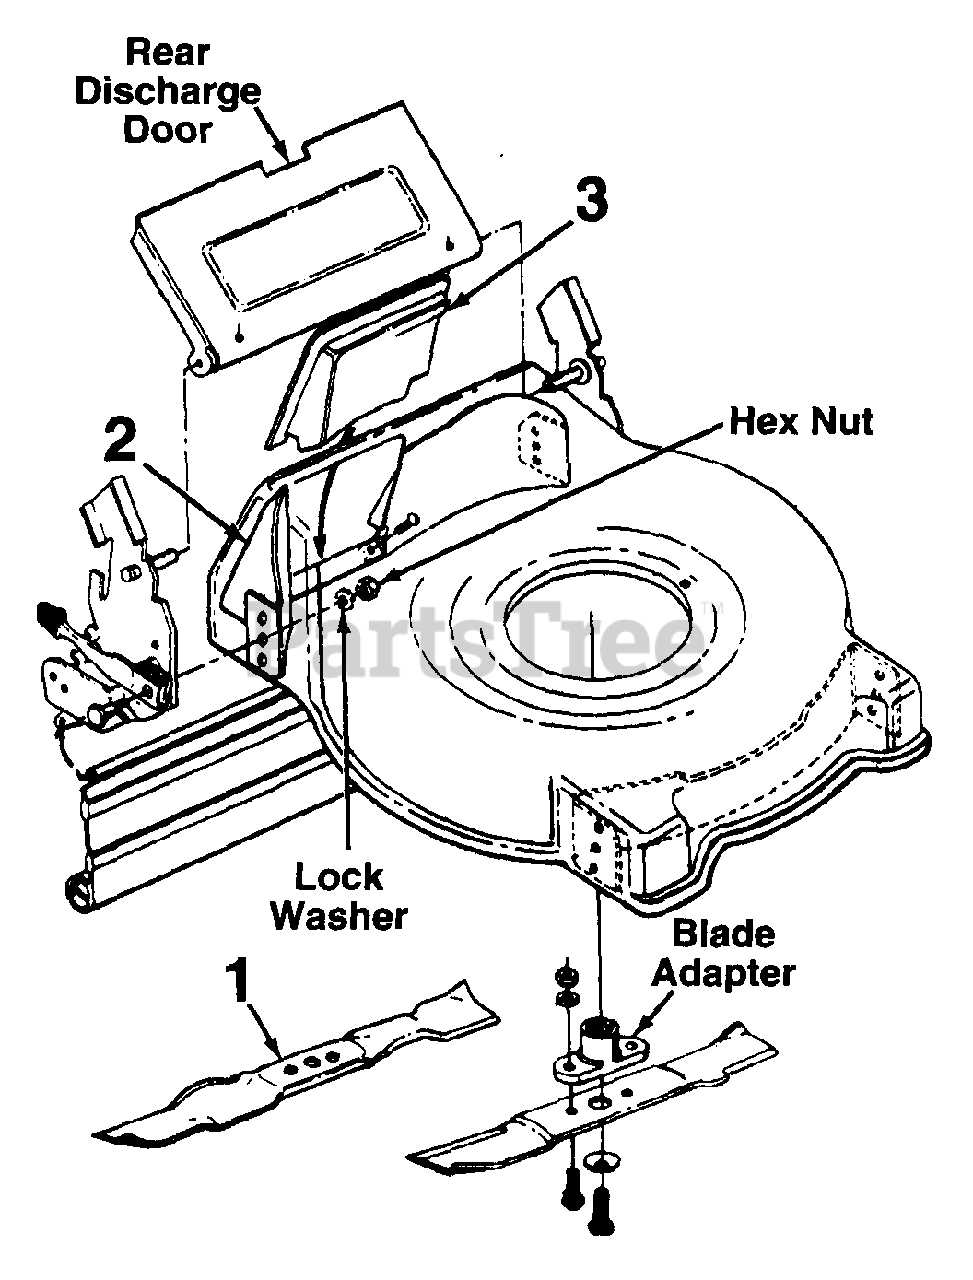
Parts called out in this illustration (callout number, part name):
1	21" Mulching Blade (082)
1	19" Mulching Blade (099)
2	Mulching Baffle - R.R.
3	Mulching Baffle Plug
